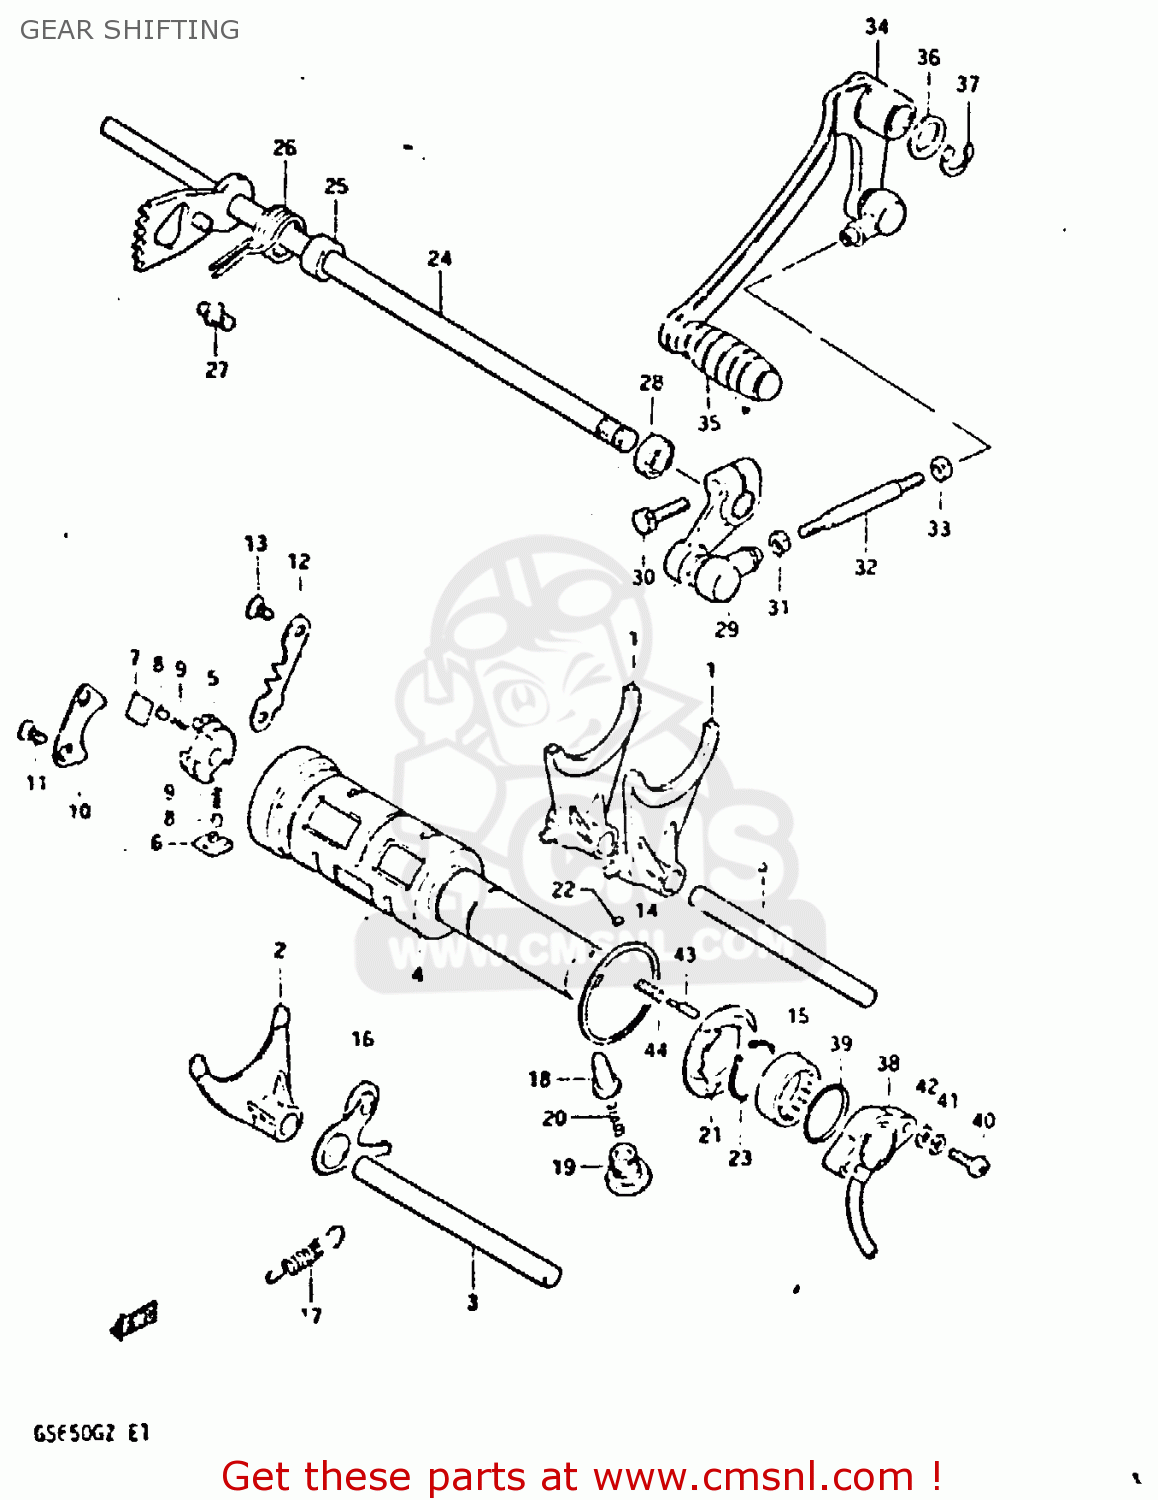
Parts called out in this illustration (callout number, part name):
1	FORK,GEAR SHIFT NO.1
2	FORK,GEAR SHIFT NO.3
3	SHAFT,GEAR SHIFT FORK
4	CAM,GEAR SHIFT
5	RETAINER,GEAR SHIFT CAM
6	PAWL,GEAR SHIFT NO.1
7	PAWL,GEAR SHIFT NO.2
8	PIN(5X8)
9	SPRING
10	LIFTER,GEAR SHIFT PAWL
11	SCREW
12	GUIDE,GEAR SHIFT
13	SCREW
14	WASHER(40X45X1)
15	BEARING
16	STOPPER,GEAR SHIFTING
17	SPRING
18	STOPPER,GEAR SHIFT CAM NO.2
19	HOLDER,GEAR SHIFT CAM STOP SPR
20	SPRING
21	PLATE,GEAR SHIFT CAM STOPPER
22	PIN 4X6
23	CIRCLIP,25MM
24	SHAFT,GEAR SHIFT
25	SPACER(12X20X15.3)
26	SPRING
27	STOPPER,GEAR SHIFT CAM
28	OIL SEAL
29	ARM,GEAR SHIFT LINK
30	BOLT
31	NUT
32	ROD,GEAR SHIFT LINK
33	NUT
34	LEVER ASSY, GEAR SHIFTING
35	RUBBER,GEAR SHIFT PEDAL
36	WASHER(12.5X20X1)
37	CIRCLIP
38	TERMINAL BASE ASSY,GEAR SHIFT
39	O-RING (D:2.4 ID:26.2)
40	SCREW 5X20
41	LOCK WASHER
42	WASHER
43	PIN(5X15.5)
44	SPRING
